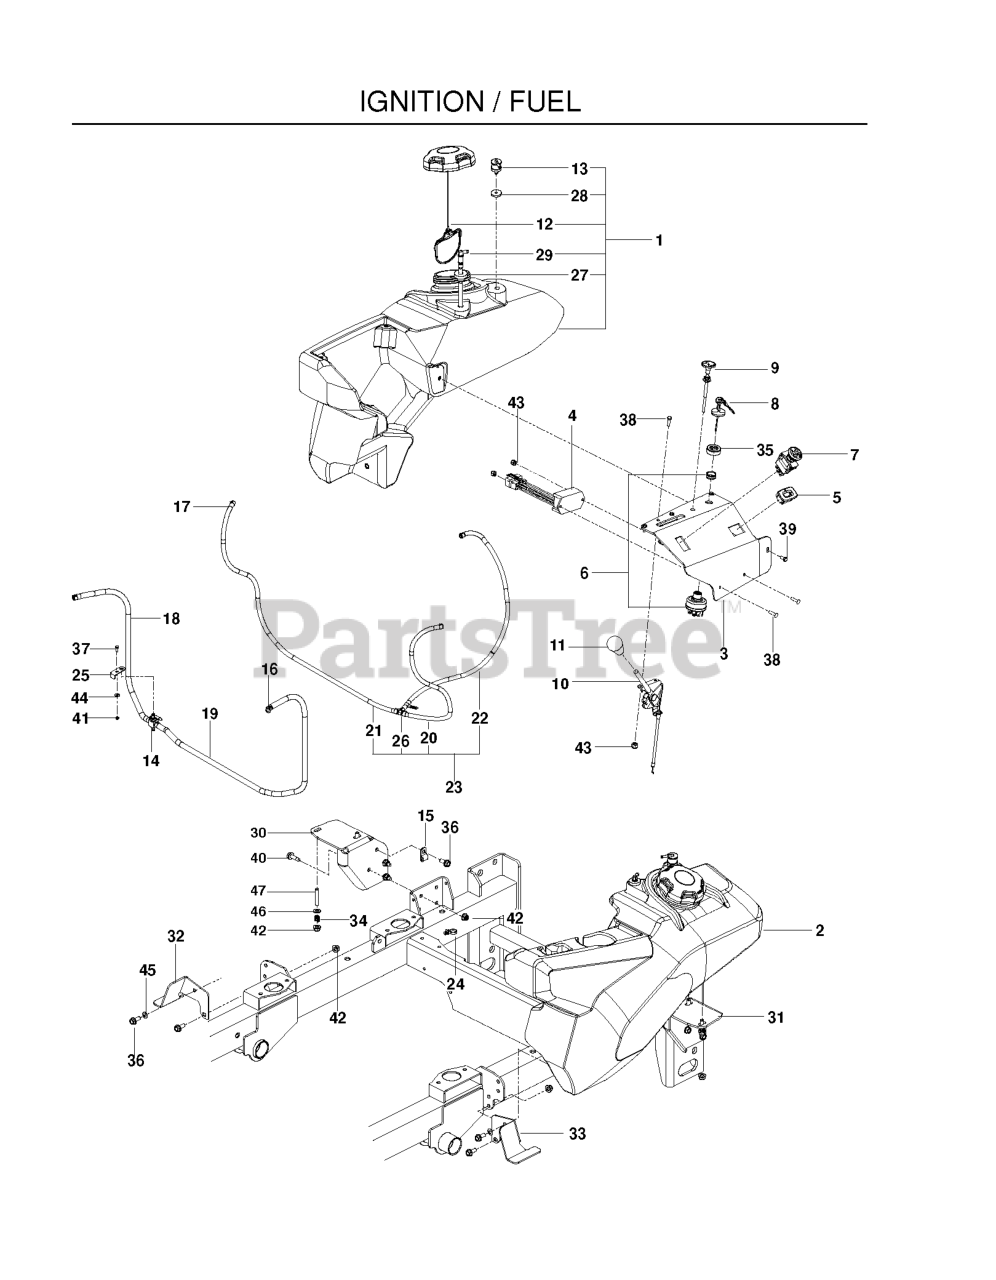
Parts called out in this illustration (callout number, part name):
1	RT FUEL TANK ASM EPA
2	LT FUEL TANK ASM EPA
3	PANEL.CONTROL.GAS.GRAY
4	TIMER, SEAT
5	HOUR METER
6	SWITCH, IGNITION, INDAK
7	SWITCH, PTO 10 AMP
8	KEY, IGNITION
9	CABLE, CHOKE, 48"
10	CABLE, THROTTLE, 46"
11	KNOB - SHIFT
12	CAP, FUEL
13	VALVE.FUEL.CHECK
14	FUEL VALVE
15	DOUBLE TUBE CLAMP
16	HOSE CLAMP
17	CLAMP, HOSE
18	LINE, FUEL, 22"
19	LINE, FUEL, 38"
20	HOSE, 3/16" VAPOR, 21"
21	HOSE, VAPOR 3/16 X 39"
22	HOSE, VAPOR 3/16 X 30"
23	ASSEMBLY, VAPOR LINE
24	TIE WRAP, 8-3/8", W/CLIP
25	BRACKET,FUEL VALVE, BLACK
26	TEE, FUEL LINE 3/16"
27	RUBBER GROMMET
28	GROMMET, CHECK VALVE
29	FITTING, FUEL
30	MOUNT, RT TANK, BLK
31	MOUNT, LT TANK, BLK
32	XX MOUNT, TANK, RT-BLK
33	MOUNT, TANK, LT-BLK
35	CAP IGNITION NUT
36	HHFS 5/16-18 X 3/4
37	HCS 1/4C X 3/4 HCS
38	SCR #10-24 X .75 SKT HD BLK
39	SCR #10-24 X 3/8 SKT HD BLK OX
40	RP BLT 5/16-18 X 1 THRD FORM D
41	JAM NUT 1/4C (2 2 PW01)
42	5/16-18 NYLOC FLANGE NUT
43	NUT 10-24 NYLOC
44	WASHER 1/4 FLAT
45	WASH 5/16 DISC SPRING ZD
46	FLAT WASHER 5/16 SAE
47	STUD, 5/16C
